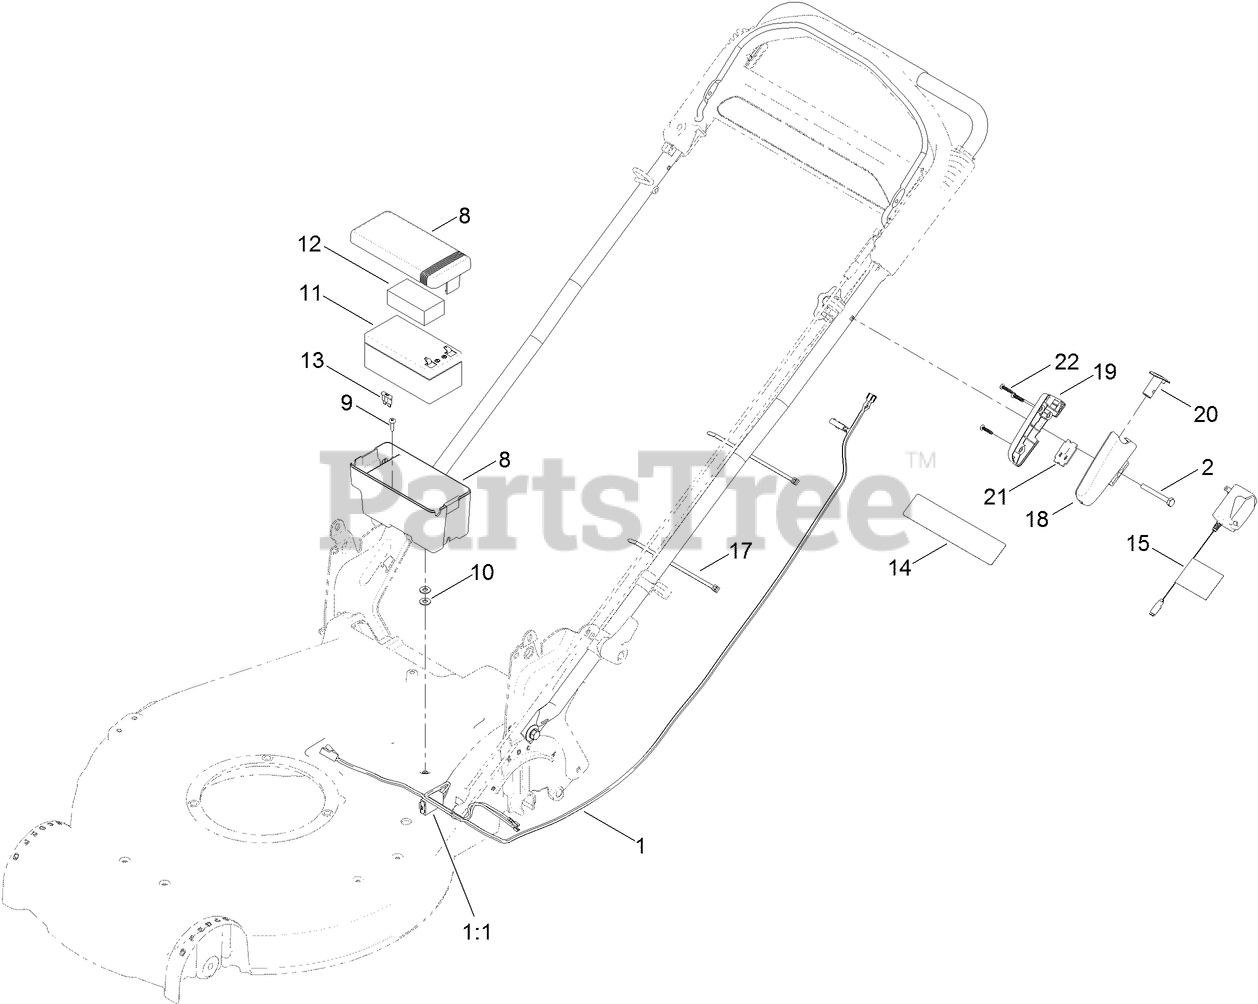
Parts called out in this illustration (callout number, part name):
1	HARNESS-WIRE
1:1	FUSE-40 AMP
2	SCREW-HH
8	BATTERY BOX ASM
10	WASHER-FLAT
11	BATTERY-WET
12	FOAM-BATTERY, TOP
13	FUSE-40 AMP
14	DECAL-WARNING
17	TIE-CABLE
20	BUTTON-SWITCH
21	SWITCH-PUSH BUTTON
22	SCREW-PPH
